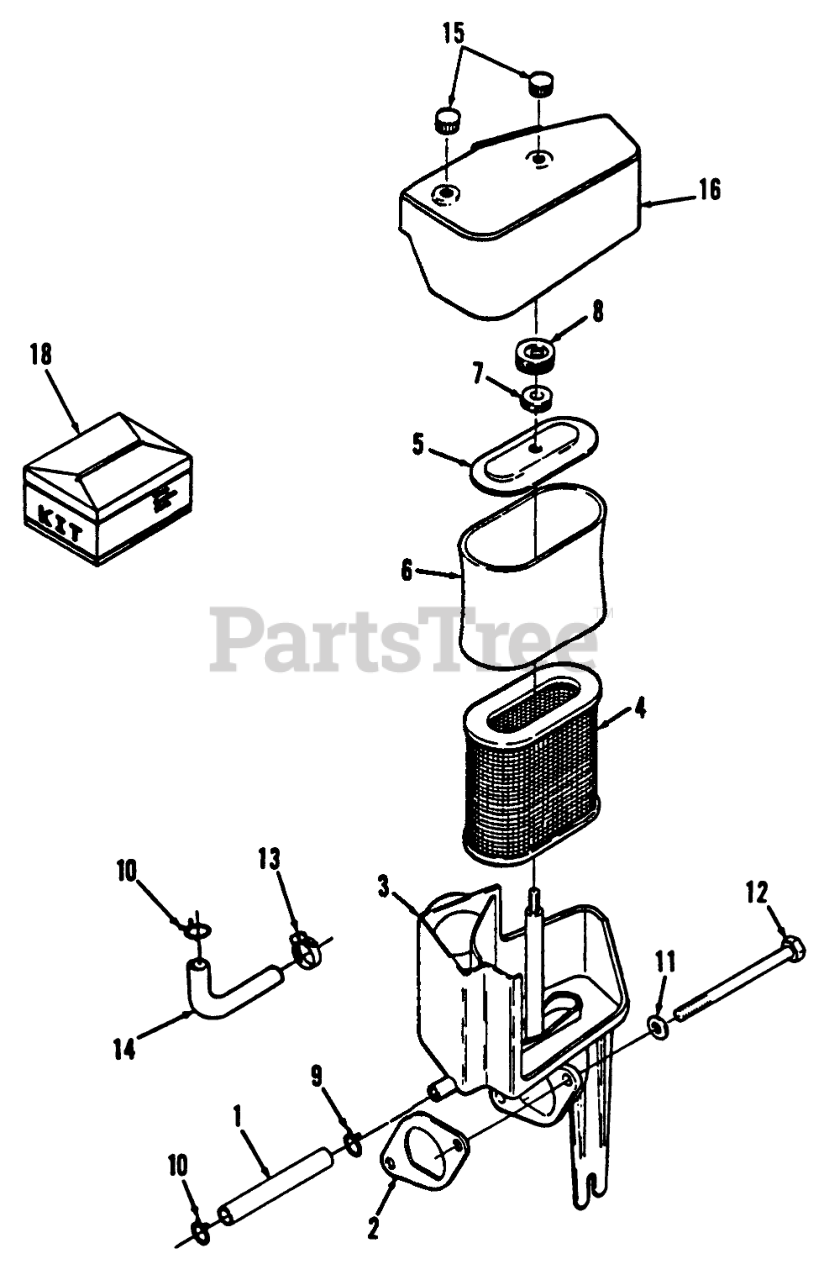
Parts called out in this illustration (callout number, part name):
1	HOSE-BRH 3/8"IDX91MM
2	Gasket
3	ADAPTER
4	AIR CLEANER ELEMENT
5	COVER-ELEMENT
6	WRAPPER-ELEMENT
7	GROMMET
9	HOSE CLAMP
10	CLAMP-HOSE
11	WASHER-FLAT
12	HHCS-M8 X 100MM
13	CLAMP-HOSE
14	HOSE-BREATHER
15	KNOB M6
16	COVER-AIR CLEANER
18	Kit-Air Cleaner (Incl. Ref. #2-8 & 13-15)
